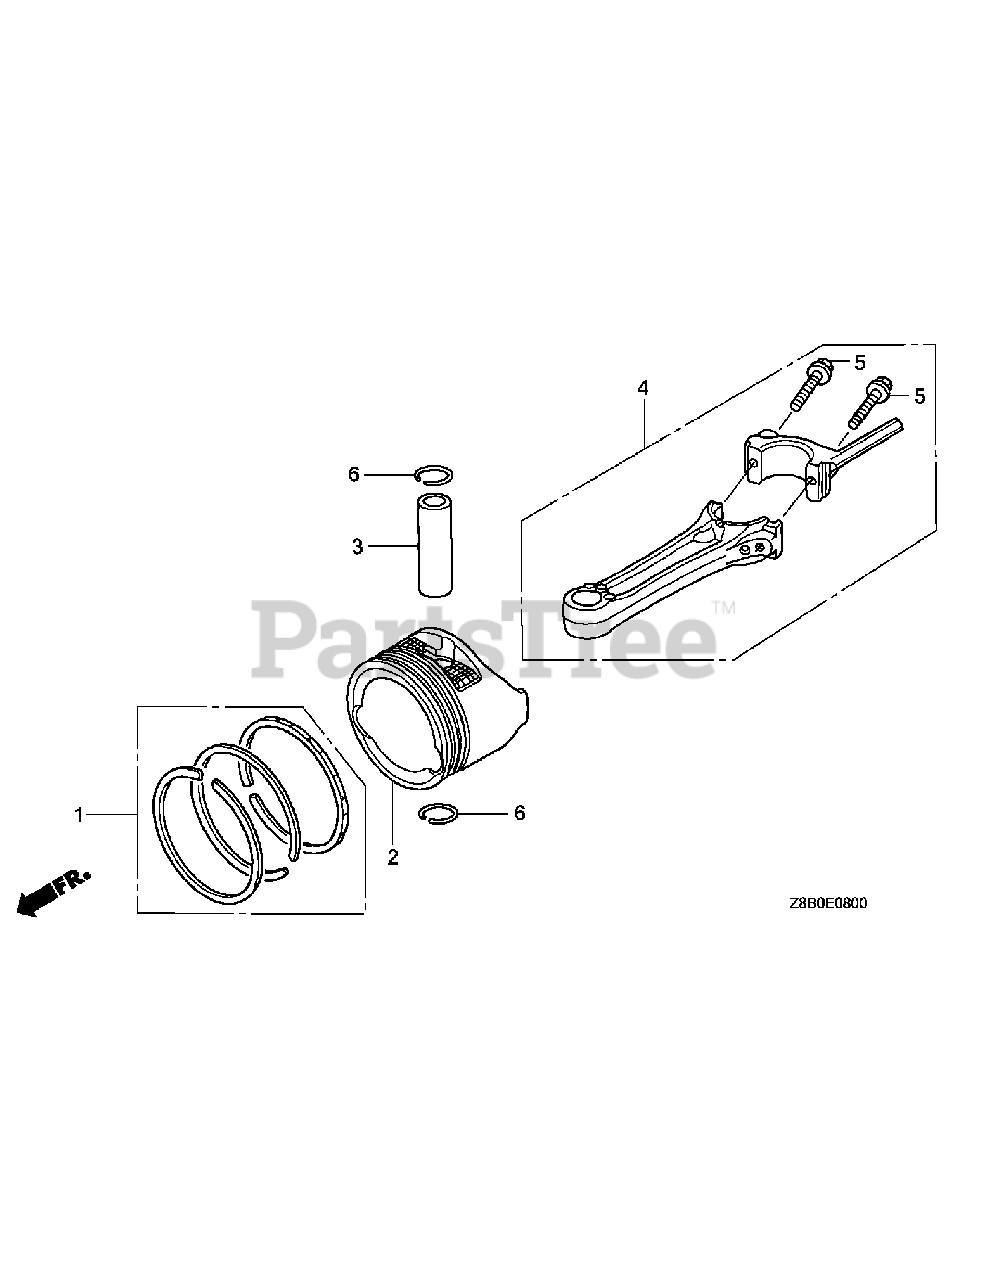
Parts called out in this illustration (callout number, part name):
1	RING SET, PISTON (STD.) (TEIKOKU)
2	PISTON
3	PIN, PISTON
4	ROD ASSY., CONNECTING
5	BOLT, CONNECTING ROD
6	CLIP, PISTON PIN, 13MM
